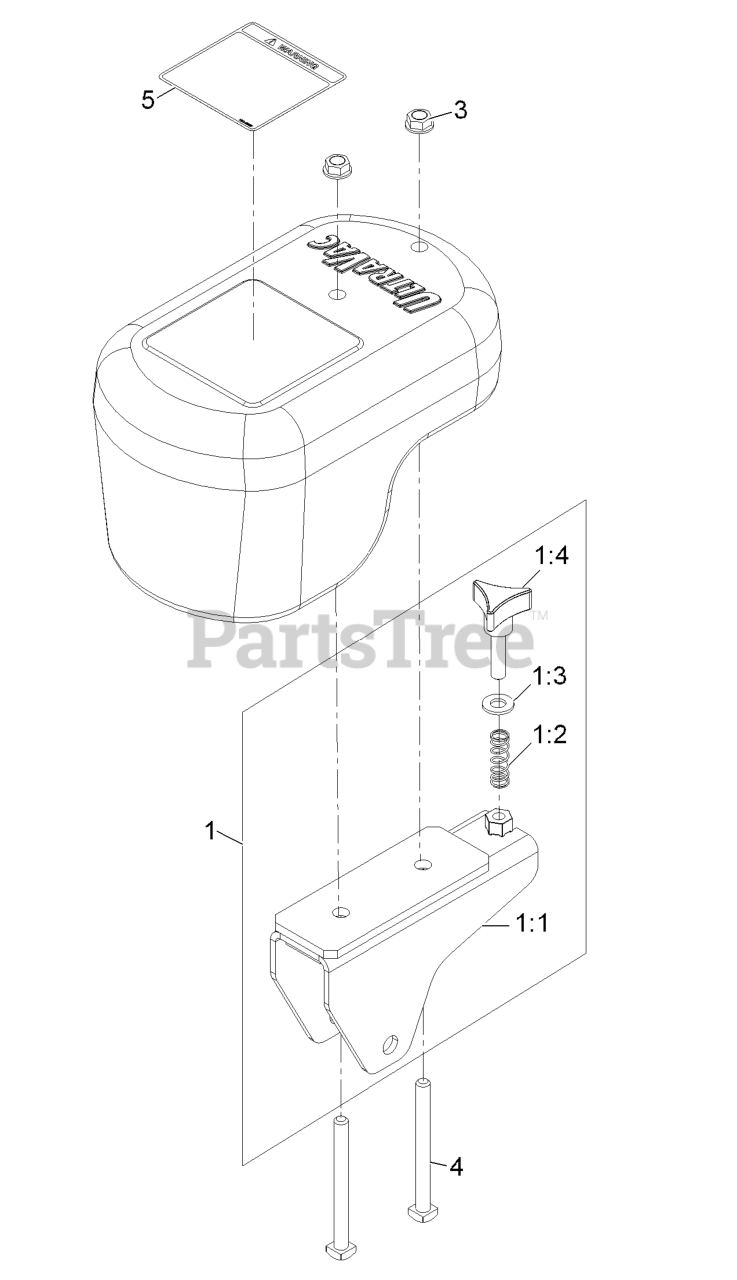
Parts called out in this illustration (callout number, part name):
1	ASM,CASTER WEIGHT BRACKET
1:1	WLD,CASTER WEIGHT BRACKET
1:3	WASHER-FLAT
3	NUT-HHF, WHIZ
4	BOLT, SQUARE HEAD YZ
5	DECAL,WEIGHT
